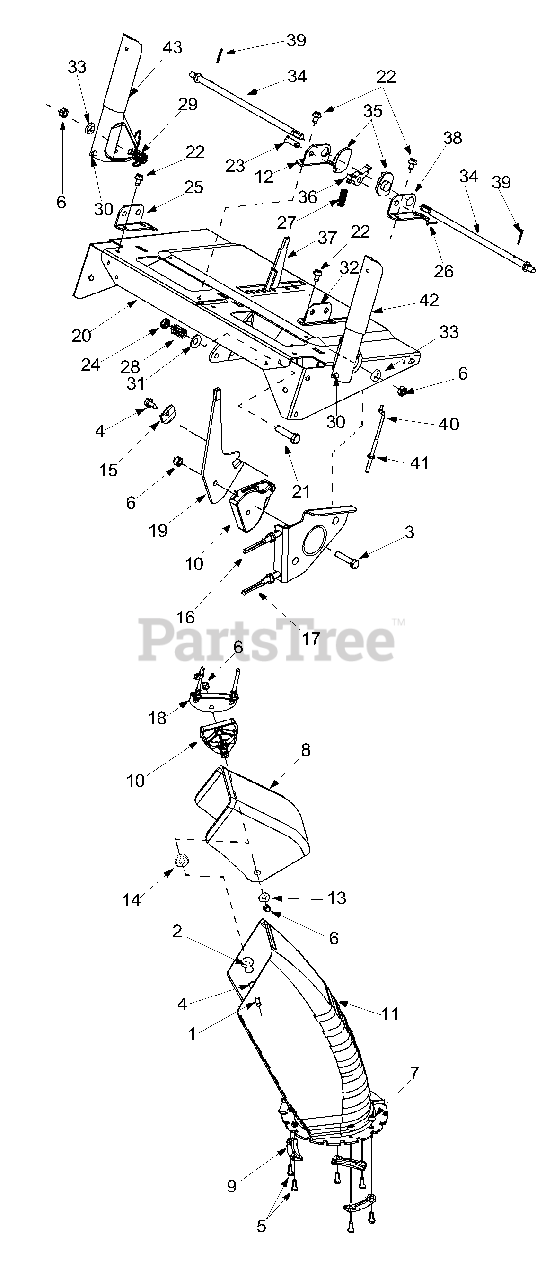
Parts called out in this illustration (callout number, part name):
1	Carriage Screw
2	Carriage Bolt 5/16-18 x 1.75"
3	Hex Bolt 5/16-18 x 1.5"
4	Hex AB Screw 1/4-14 x .625"
5	Hex Screw 1/4-20 x .75"
6	Hex Lock Nut
7	Hex Flange Lock Nut
8	Upper Chute
9	Chute Flange Keeper
10	Cable Guide: Chute Tilt
11	Lower Chute
13	5/16 Washer
15	Special Washer
16	Chute Control Cable
17	Chute Cable w/Clip
21	Hex Bolt 3/8-24 x 1.5"
22	TT Screw 1/4-20 x 0.5"
23	Clevis Pin
26	Cotter Pin
29	Torsion Spring
30	Rubber Bumper
31	Bell Washer
33	Special Washer
35	Cam: Handle Lock
36	Pawl: Handle Lock
40	Z Fitting Cable
41	Hex Jam L-Nut 3/8-24 Thd.
42	Handle Ass'y LH
43	Handle Ass'y RH
